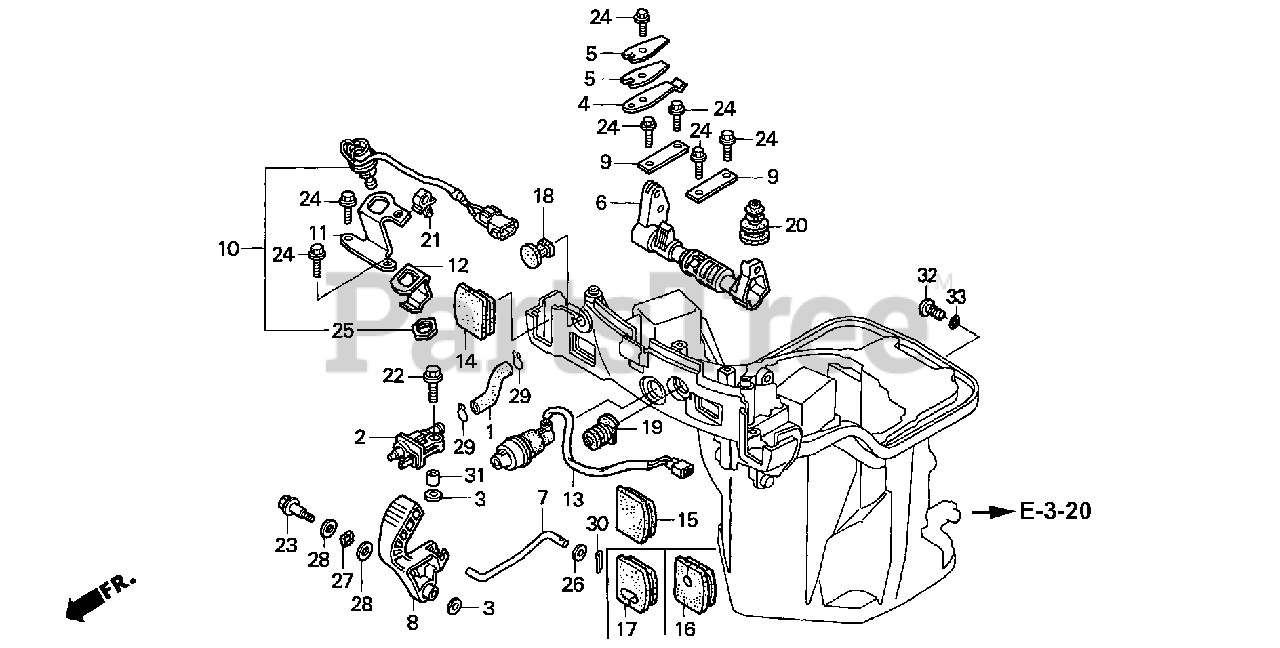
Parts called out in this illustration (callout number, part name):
1	TUBE A, FUEL
2	CONNECTOR ASSY., FUEL (B)
3	WASHER, PIVOT
4	SPRING, CLICK
5	SPRING, CLICK ASSIST
6	SHAFT, SHIFT
8	LEVER, SHIFT
9	PLATE, SHIFT SHAFT
10	SWITCH ASSY., NEUTRAL
11	BRACKET, NEUTRAL SWITCH
12	PLATE, NEUTRAL SWITCH
13	LAMP ASSY., INDICATOR
14	GROMMET A, OIL CASE
17	GROMMET B, OIL CASE
18	GROMMET F, OIL CASE
19	GROMMET D, OIL CASE
20	GROMMET E, OIL CASE
21	CLIP A, BRAKE PIPE
22	BOLT, FLANGE (6X22) (CT200)
23	BOLT, REVERSE LOCK
24	BOLT, FLANGE (5X12) (CT200)
25	NUT, HEX. (20MM)
26	WASHER, PLAIN (5MM)
27	WASHER, WAVE (10MM)
28	WASHER, PLAIN (9MM)
29	CLIP, TUBE (B12)
30	PIN, SPLIT (2.0)
31	COLLAR, DISTANCE (6MM)
